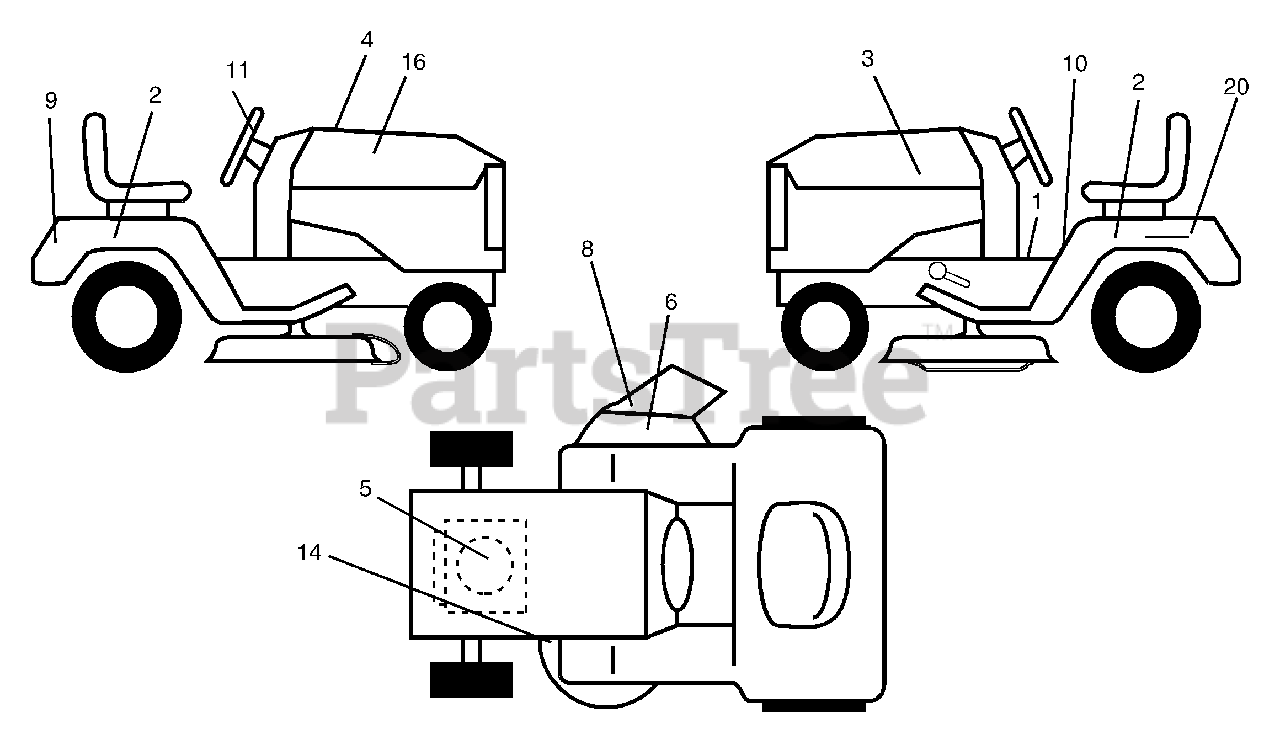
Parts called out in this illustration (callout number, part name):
2	Decal Fender Side
3	Decal Hood LH
4	Decal Replace
5	Decal HP Engine
6	Decal Deck "B" 42"
8	Decal Warning Mult-Language
9	Decal Fender Logo
10	Decal Fender Danger E/F
11	Decal Ins Strg Whl
14	Decal V-Belt Schematic
16	Decal Hood Rh
20	Decal Bat Dan/Psn
